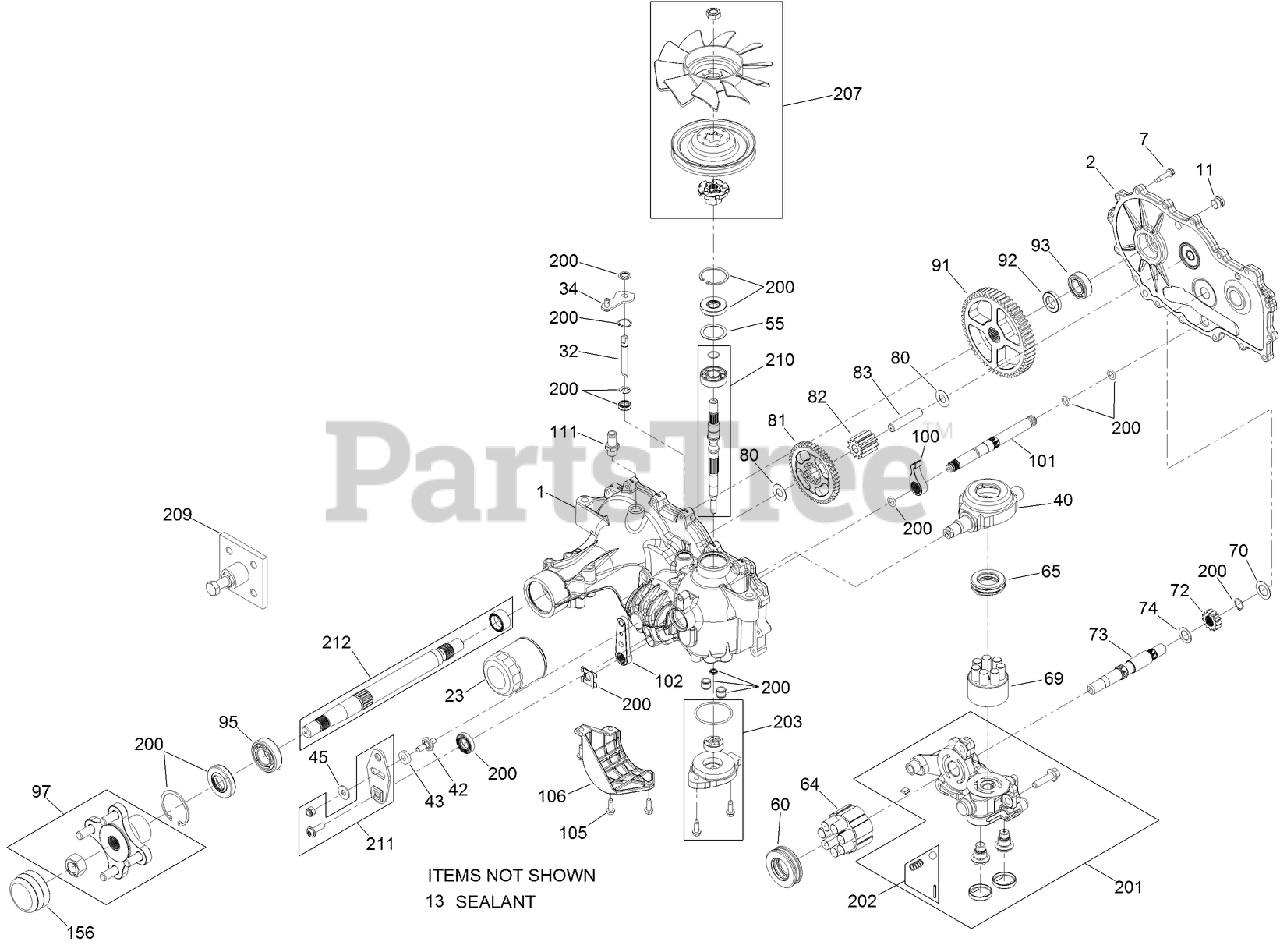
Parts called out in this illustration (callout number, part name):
1	MAIN HOUSING KIT
2	RH HOUSING SIDE KIT
7	SCREW-HHF
11	PLUG-THREAD, STRAIGHT
23	ELEMENT-OIL FILTER, HYD
32	ROD-BYPASS
34	ARM-BYPASS
40	SWASHPLATE-TRUNNION
43	PUCK-FRICTION
45	WASHER
55	SPACER
60	BEARING-THRUST
64	MOTOR CYLINDER BLOCK KIT
65	BEARING-THRUST
69	PUMP BLOCK ASM
70	WASHER-FLAT
72	GEAR-13T
73	SHAFT-MOTOR
74	WASHER
80	WASHER
81	GEAR-46T
82	GEAR-11T
83	PIN-JACKSHAFT
91	GEAR-54T
92	SPACER
93	BEARING-BALL
95	BEARING-BALL
97	HUB KIT
100	PAWL-BRAKE
101	BRAKE SHAFT KIT
102	HANDLE-BRAKE
106	GUARD-FILTER, RH
111	ADAPTER-STRAIGHT
156	COVER-NUT, AXLE
200	SEAL KIT
201	RH CENTER SECTION CHARGE KIT
202	CHARGE RELIEF KIT
203	CHARGE KIT
207	FAN AND PULLEY KIT
209	PULLER-HUB, 4 BOLT
210	INPUT SHAFT KIT
211	CONTROL ARM KIT
212	AXLE SHAFT KIT
